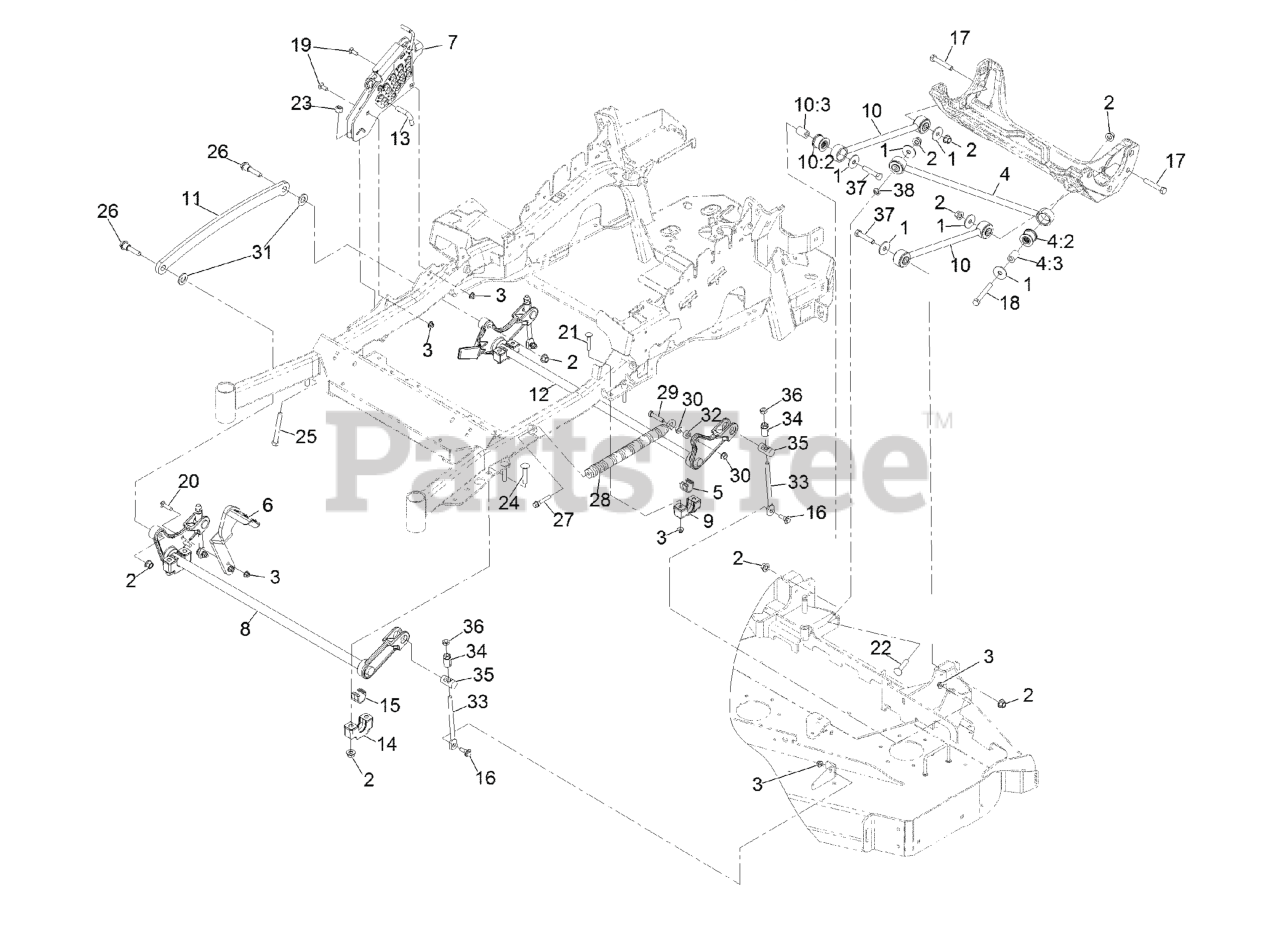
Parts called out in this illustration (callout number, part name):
1	WASHER-THRUST
2	Nut-Lock 1/2-13
3	NUT-HF, NI
4	PANHARD ROD ASM
4:2	BUSHING-SUSPENSION, RUBBER
5	BEARING-CROSS SHAFT, REAR
6	LEVER-FOOT
7	HOC ASM
8	DECKLIFT-FRONT
9	SUPPORT-CROSS SHAFT, BEARING REAR
10	DECK STRUT ASM
10:2	BUSHING-SUSPENSION, RUBBER
11	LINK-LIFT, DECK
12	LIFT-DECK, REAR
13	PIN-HOC
14	SUPPORT-CROSS SHAFT, BEARING
15	BEARING-CROSS SHAFT, FRON
16	SCREW-SHOULDER, HHF
17	SCREW-HH
18	SCREW-HH
19	BOLT-CARR
20	SCREW-CARR
21	Bolt-Carriage 3/8-16 X 2 1/4
22	SCREW-CARR
23	NUT-LOCK, NI
24	Bolt-Carriage 1/2-13 X 2 1/2 Spl Neck
25	BOLT-TAP
26	SCREW-HHF, SHOULDER
27	BOLT-SHOULDER
28	SPRING-EXTENSION
29	SCREW-HH
31	WASHER-FLAT
33	LINK-ADJUSTER, DECK LIFT
34	ADJUSTER-LIFT, DECK
35	TRUNNION
36	NUT-JAM
37	SCREW-HH
38	NUT-PUSH
